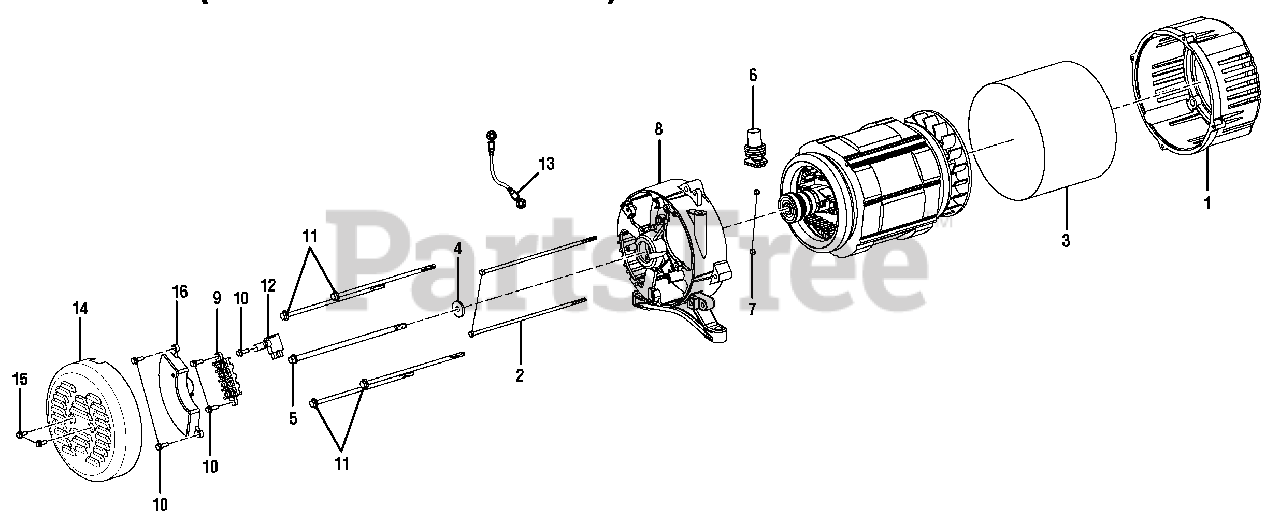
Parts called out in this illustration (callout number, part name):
1	ADAPTOR HOUSING
2	BOLT (M5, HEX HD.)
3	GENERATOR HEAD COVER
4	LOCK WASHER (5/16)
5	ROTOR BOLT (170 MM)
6	RUBBER BOOT
7	HEX NUT (M5)
8	BEARING HOUSING
9	TERMINAL BLOCK
10	BOLT (M5 X 16 MM)
11	STATOR BOLT (170 MM)
12	BRUSH ASSEMBLY
13	BONDING WIRE
14	BRUSH COVER
15	BOLT (M5 X 12 MM)
16	AUTOMATIC VOLTAGE REGULATOR
